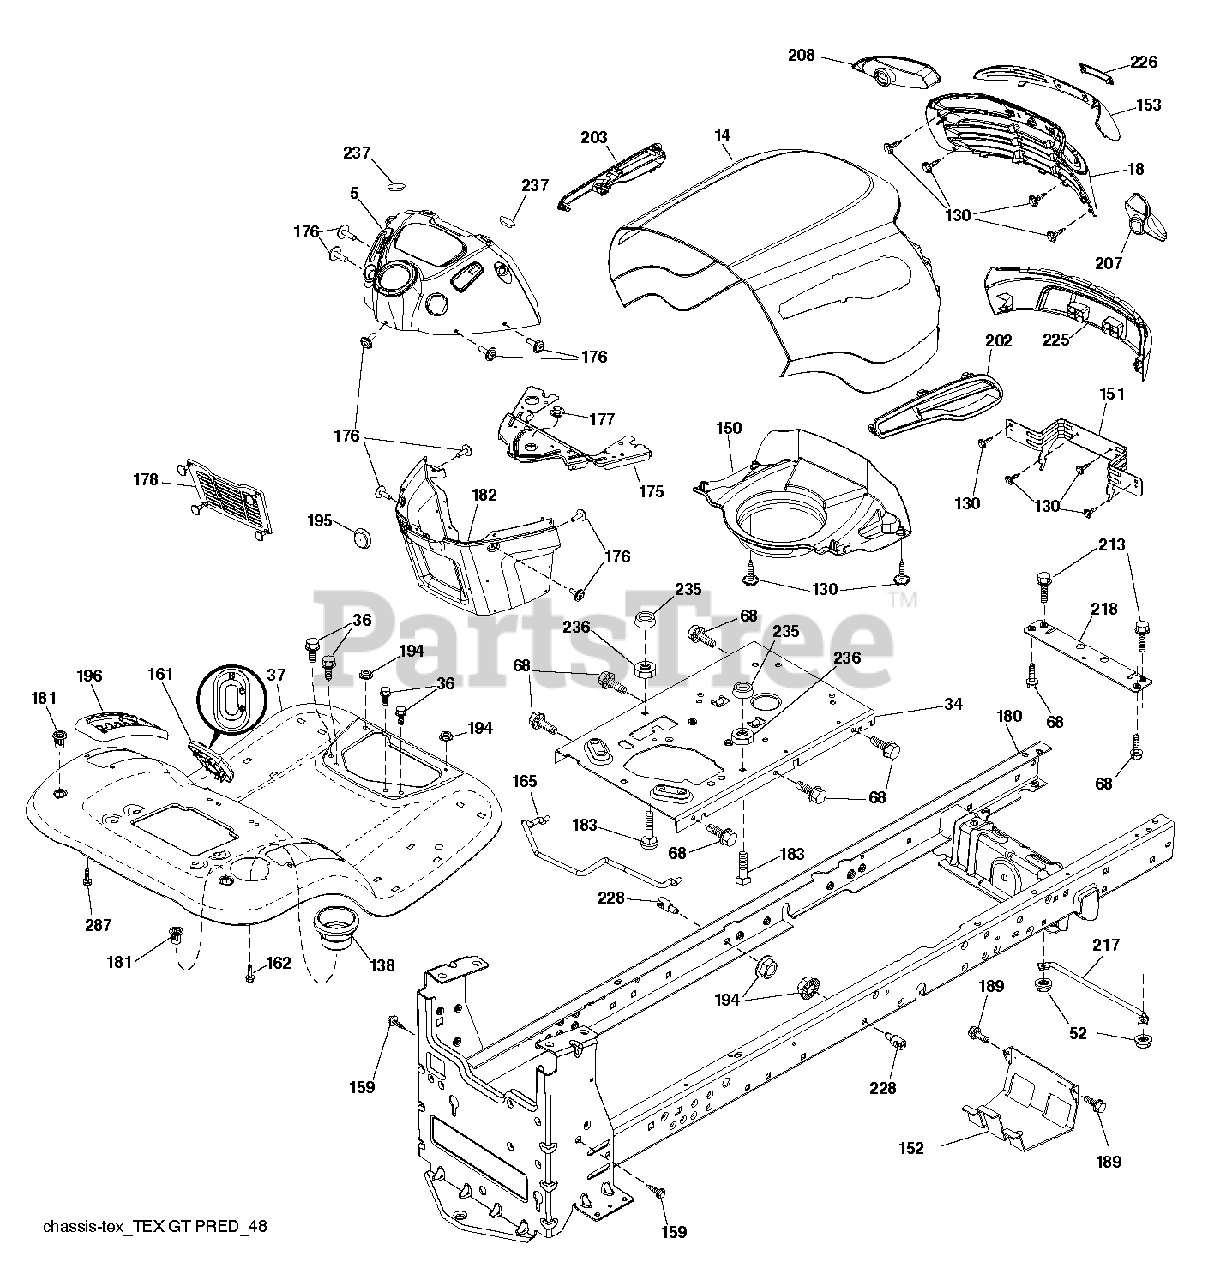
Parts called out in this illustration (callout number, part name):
34	PLATE.ENGINE.WELDED.CHASSIS
36	SCREW 5/16"
52	LOCKNUT
130	SCREW.#10 X 0.750.BOS THREAD
138	CUPHOLDER.TL.TEX.BLACK
152	SHIELD BROWNING
159	SCREW, 3/8-16X3/4
161	WINDOW.FUEL.LT.TEX.BLACK
162	SCREW.HI-LO.CONSOLE
165	SUPPORT.TANK.REAR.W/TE
175	PLATE.CROSSMEMBER.HUSQ
176	SCREW.#10-24X5/8.RN.QU
177	BUSHING,STEERING
178	CARGO.ASM.NET.TXGT.W/C
180	CHASSIS
181	FEND/FTRST.PCH.CPH.NFW
182	DASH.LOWER.COMMON.12V.ADAPTOR
183	BOLT.5/16-18X1-1/4 FULL THD
189	SCREW
194	NUT LOCK HEX FLANGE 5/16-18
195	PLUG.HOLE.DASH.LOWER.12V.BLK
196	CONSOLE.ASM.DECKLFT.BL/RBT.TLT
213	BOLT
217	ROD.PIVOT.HOOD
218	X-PIECE.HOOD.STOP.NON/
228	STUD.FASTNER.W/ANTI-ROTATE
235	SPACER FENDER
236	NUT.CENTERLOCK.5/16-
237	PLUG.MOUNT.CARGO.BLK
